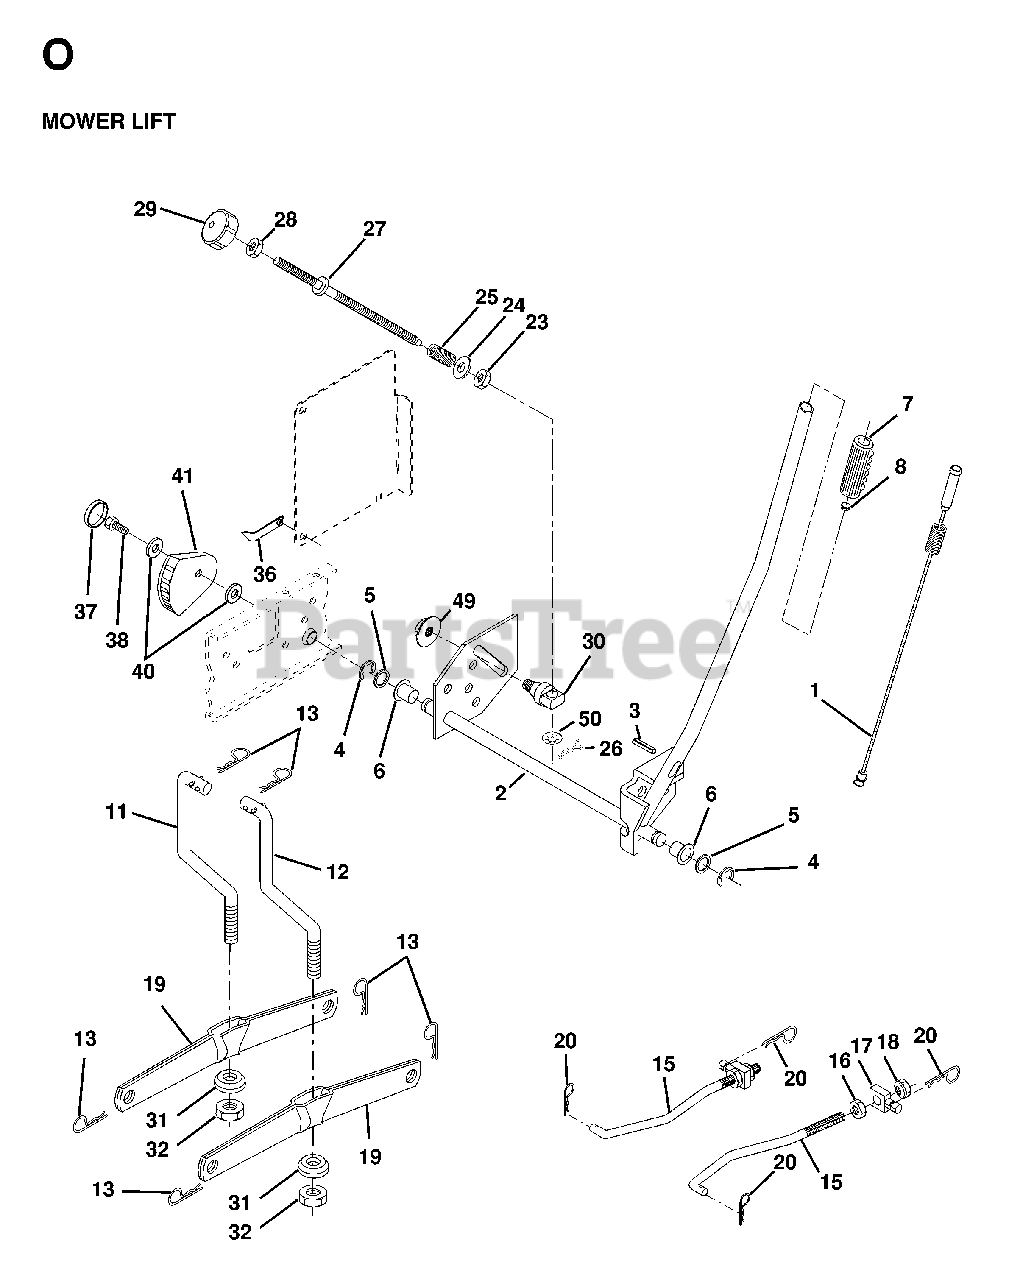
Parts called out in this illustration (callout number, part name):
1	WIRE ASM INNER W/ PLUNGER LT
2	SHAFT ASM R HANDLE
3	PIN GROOVE
4	RETAINING RING LT
6	BEARING.NYLON
7	GRIP HANDLE
8	PLUNGER BUT KIT
11	LINK LIFT LH
12	LINK LIFT RH
13	RETAINER-SPRNG RB
15	FRONT LINK
16	NUT
17	TRUNION
18	NUT
19	ARM.REAR.SUSPENSION
20	SPRING RETAINER
25	SPRING**
26	COTTER PIN
27	ROD ADJ LIFT
28	NUT
29	KNOB INF 3/8-16
31	BEARING PIVOT
32	NUT CROWNLOCK 3/8-24
36	POINTER, HEIGHT INDICATOR
37	PLUG,HOLE
38	SCREW
41	IND. HEIGHT STLT
49	NUT
50	NUT PUSH M
